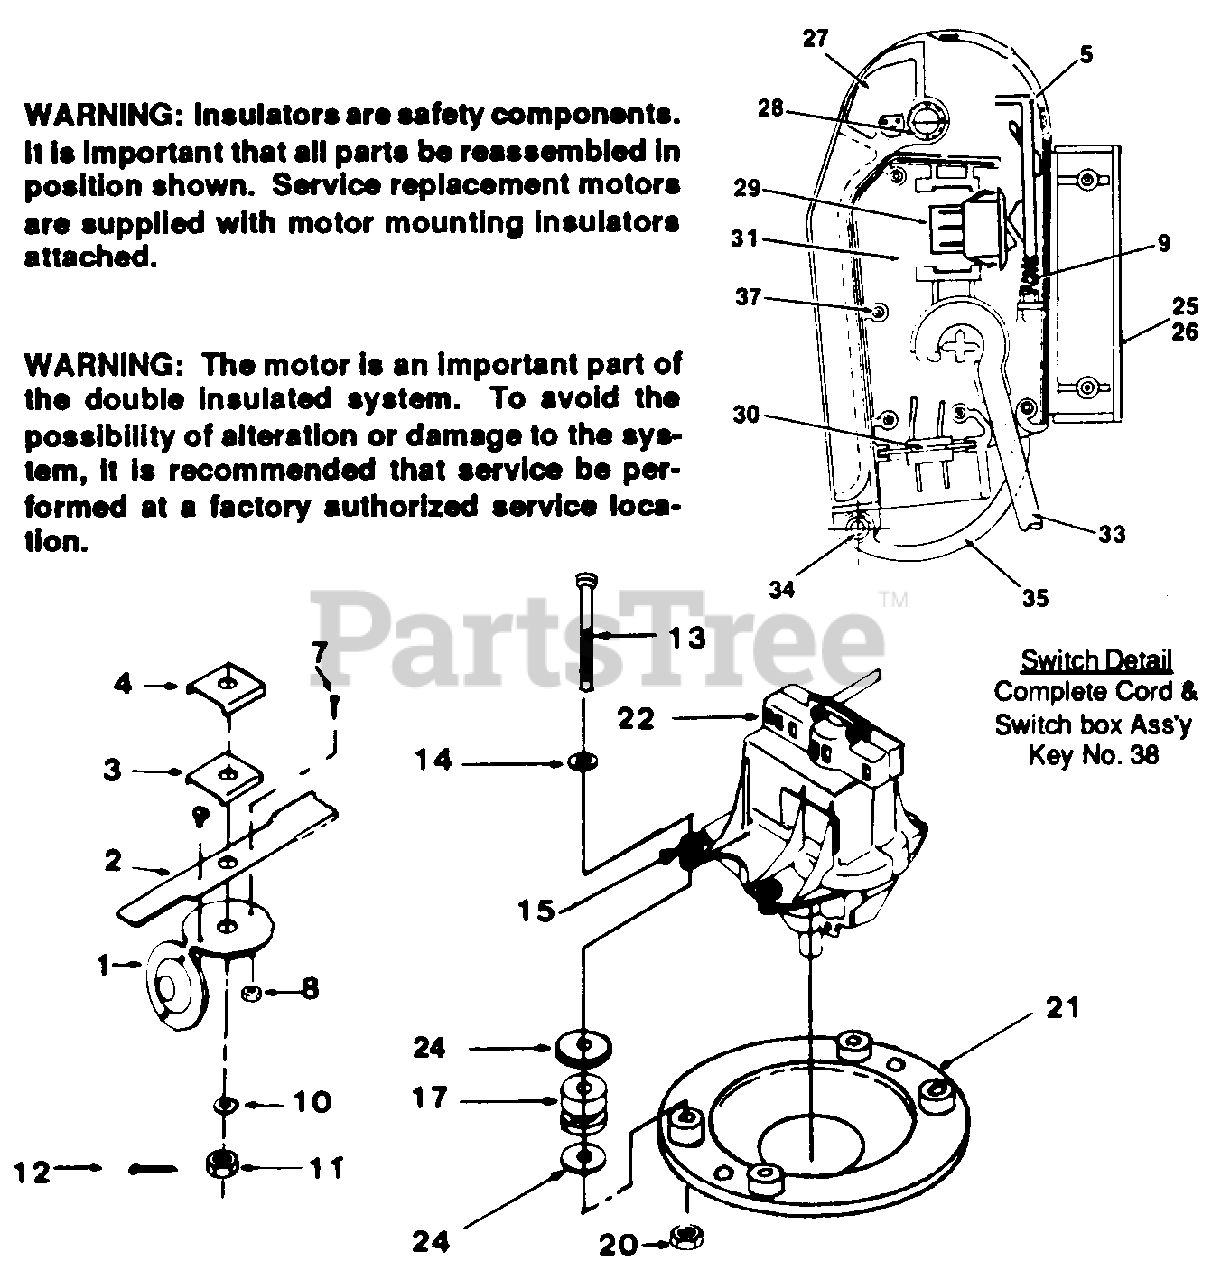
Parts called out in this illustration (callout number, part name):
1	Blade Inwlator
2	Blade 19"
3	Adaptor Insulator
4	Blade Adaptor
5	Latch
7	Bolt - Carriaoe 5/16-18 x 3/4
8	Lorknut 5/16-18
9	Latch Spring
10	Washer
11	Nut
12	Cotter Pin (Stainless Steel)
13	Saew
14	Washer
15	Inwlator
17	Grommet Assembly
20	Locknut 1/4" - 20
21	Motor Shield
22	Motor & Switch Ass'y Complete
24	Washer
25	Housing - Upper Half
27	Handle- Switch
28	Spring
29	Switch
30	Plug Assembly
33	Cord Assembly
34	Spring- Plug Retainer
35	Plub Retainer
